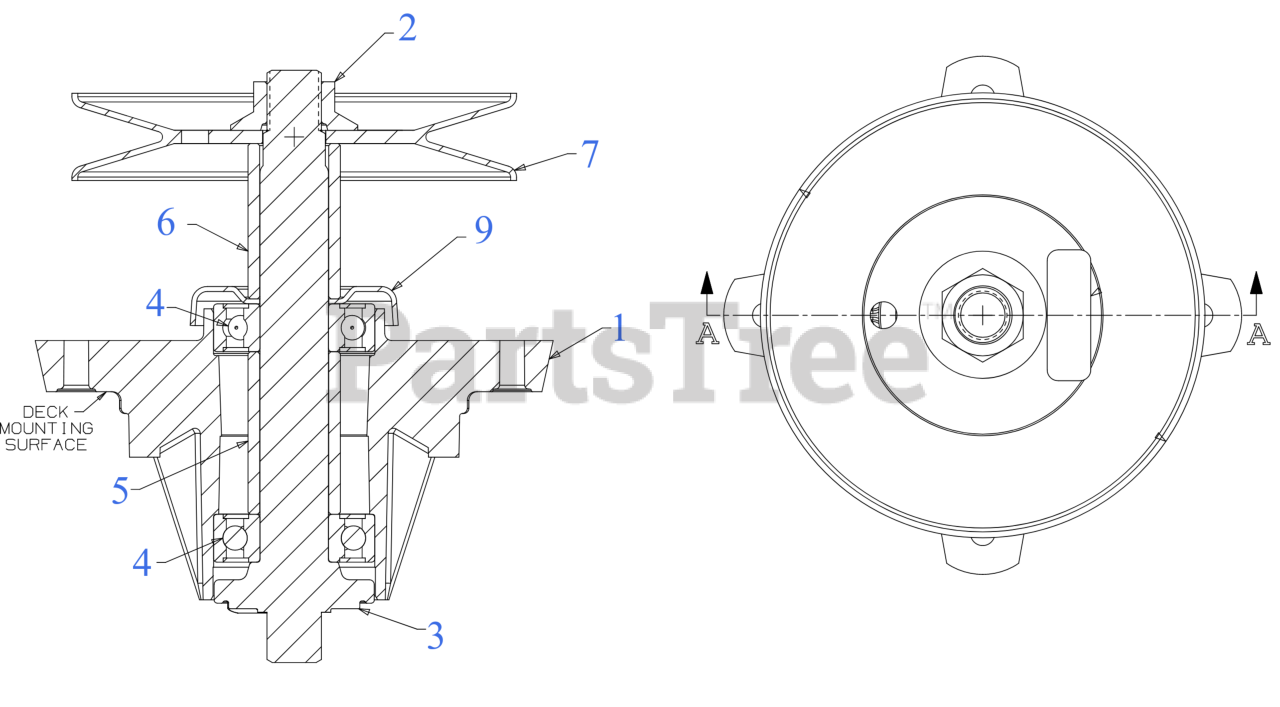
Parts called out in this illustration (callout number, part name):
1	DECK SPINDLE HOUSING
2	FLANGE NUT 5/8-18
3	SPINDLE SHAFT
4	BALL BEARING
5	SPACER- .792 x 1.060 x 1.860
6	SPACER .792 x 1.060 x 1.782
7	SPINDLE PULLEY 5.2 DIA
9	SHIELD-BRG DECK
